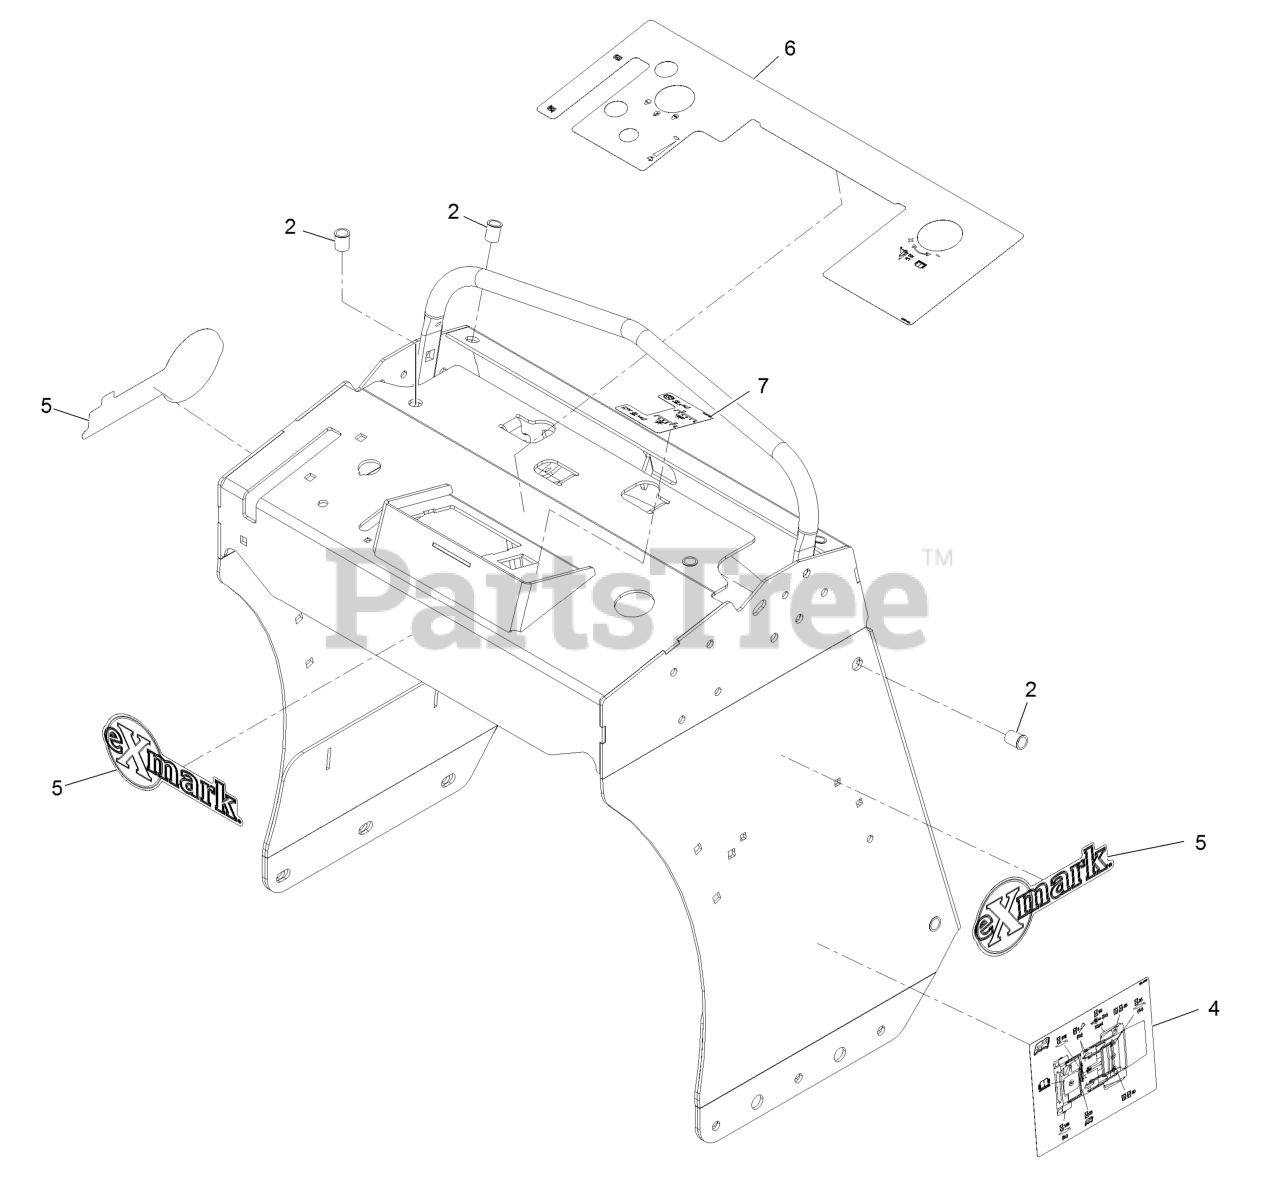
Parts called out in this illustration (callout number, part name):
2	Nut-Insert
4	Decal-Aid, Service
5	Decal, Exmark Logo
6	Decal-Panel, Control
7	Decal-Control, Tine
